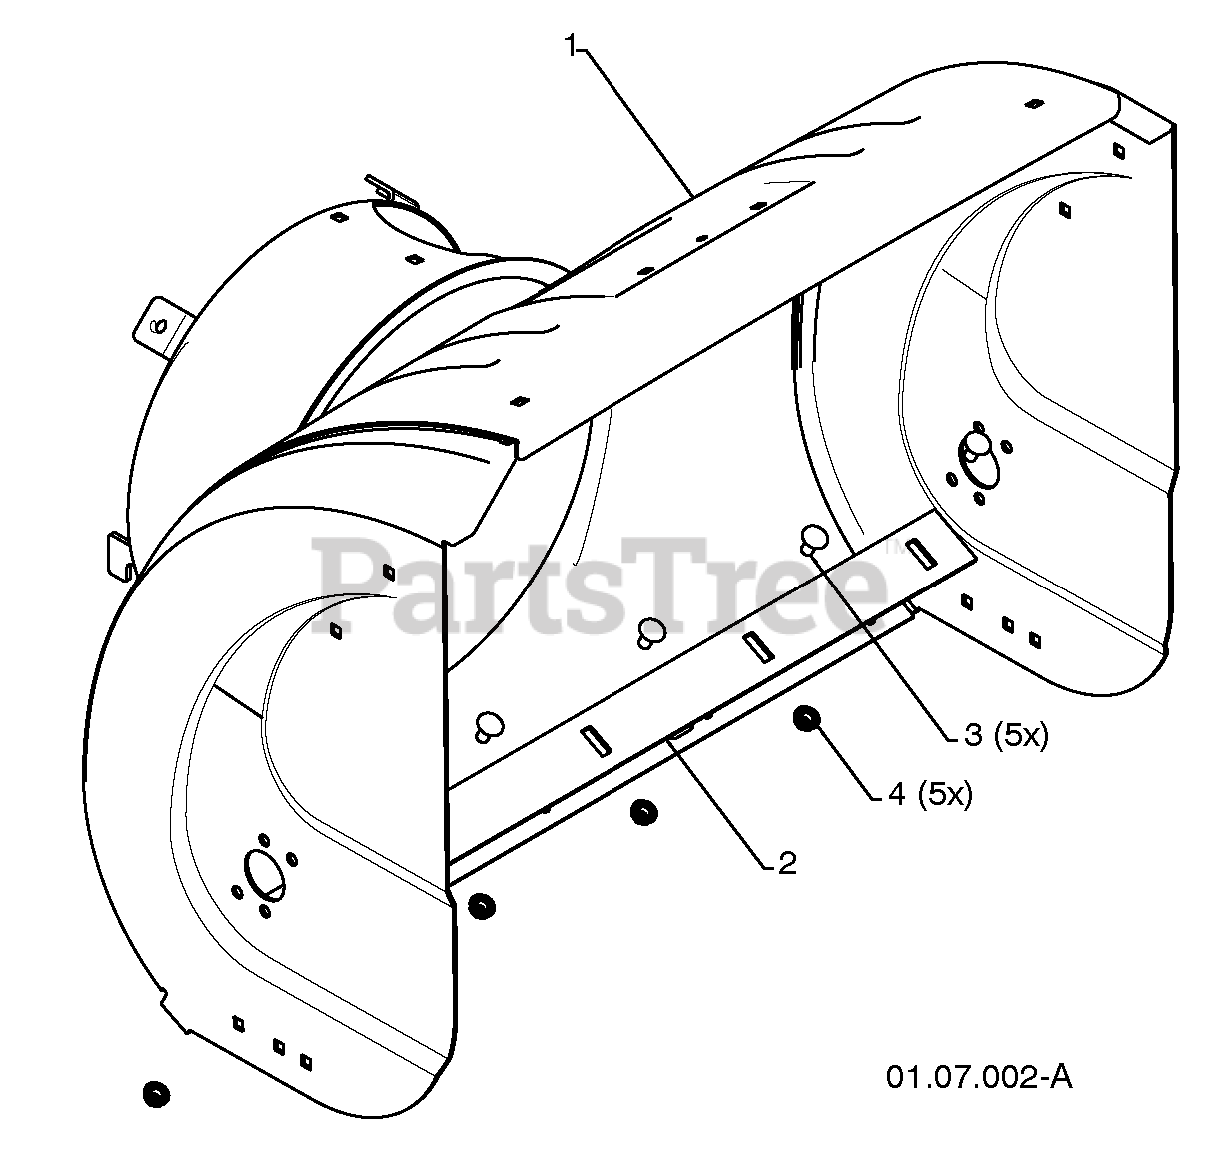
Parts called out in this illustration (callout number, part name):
1	HOUSING, AUGER
2	BAR, SCRAPER
3	BOLT
4	NUT.FLANGE.5/16
